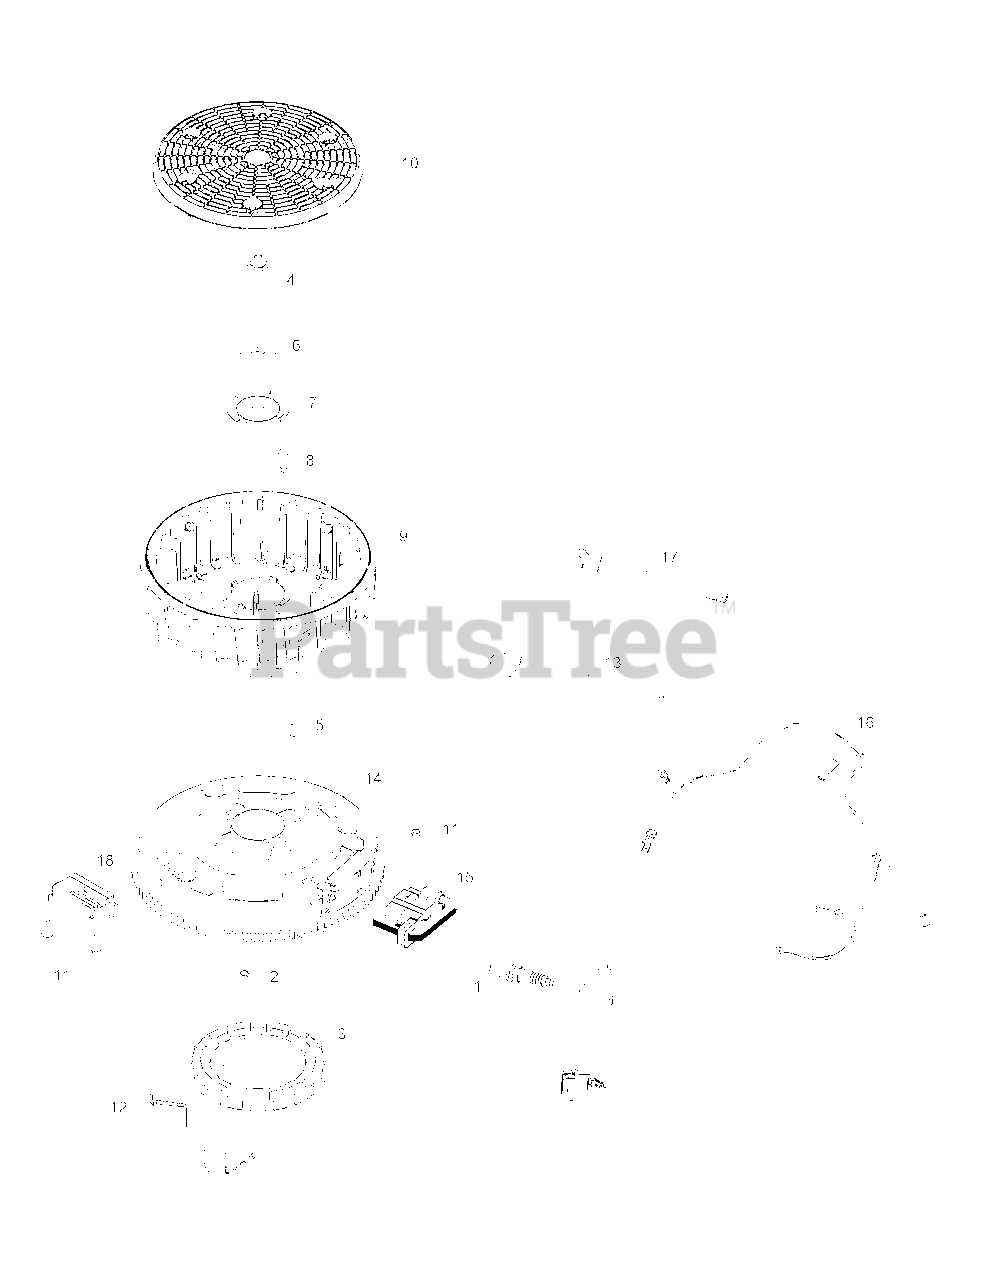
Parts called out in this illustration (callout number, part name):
2	Thread Forming Screw
3	15 Amp Stator Kit
4	Hex Flange Screw
7	Fan Mounting Plate
8	Flywheel Fan Retainer
11	Thread Forming Screw
14	Flywheel Assembly
15	Ignition Module
16	Wiring Harness
18	Rectifier Regulator
